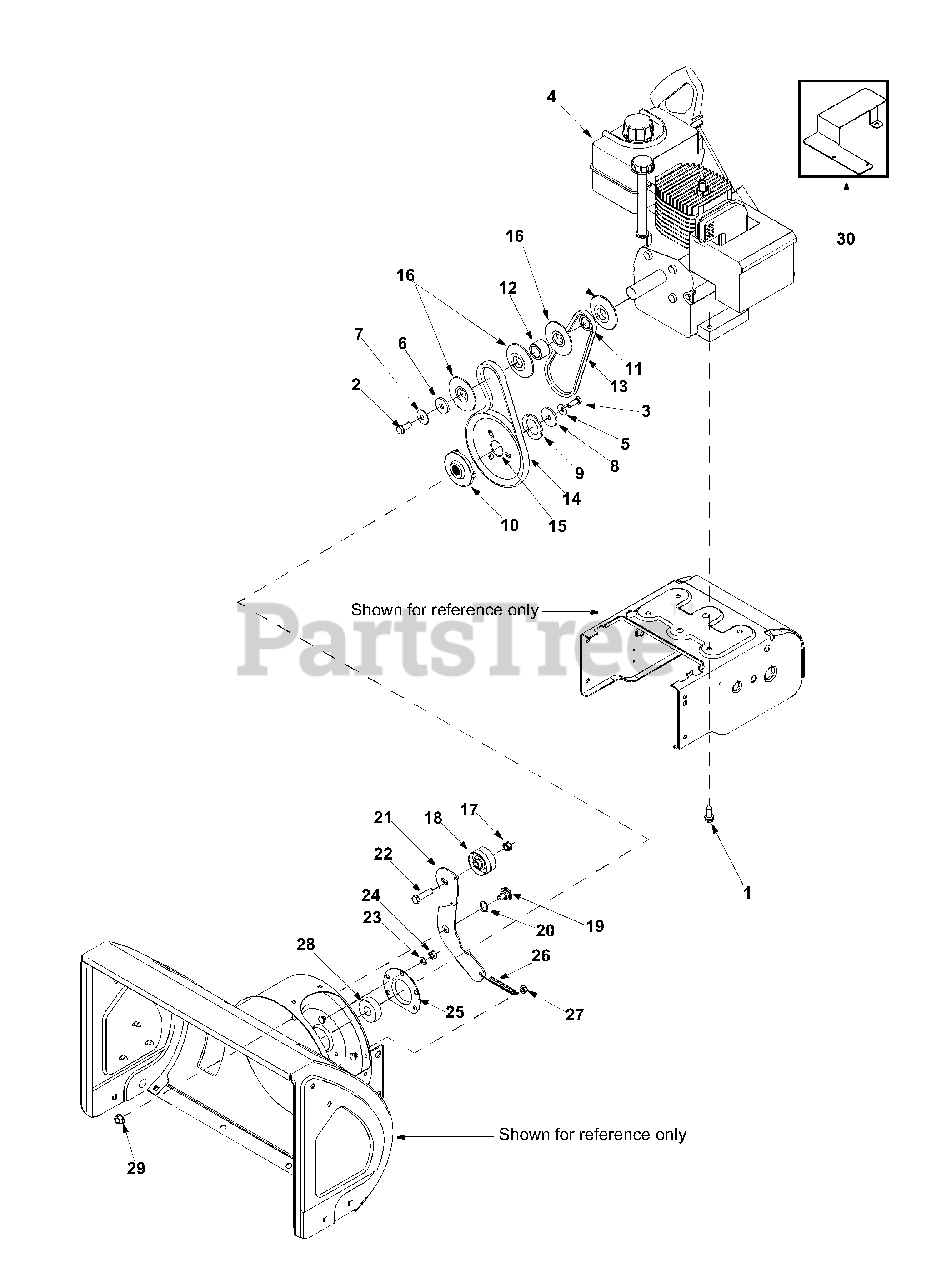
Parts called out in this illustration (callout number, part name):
1	TT Sems Screw 3/8-16 x 1.0"
2	Hex Bolt 3/8-24 x 0.875"
3	Lock Bolt 5/16-24 x 0.875"
4	Engine
5	Bell Washer
6	Flat Washer
7	Bell Washer
8	Flat Washer
9	Special Washer
10	Pulley: Adapter
11	Spacer
12	Spacer
13	V-Belt
14	V-Belt
15	Auger Pulley
16	Pulley Half
17	Hex Lock Nut 3/8-16
18	Flat Idler
19	Shoulder Screw 3/8-16
20	Wave Washer
21	Auger Idler Bracket
22	Hex Bolt 3/8-16 x 1.50"
23	Lock Washer 5/16
24	Hex Nut 5/16-18
25	Bearing Housing
26	Extension Spring
27	Patch Nut
28	Ball Bearing
29	Flange Lock Nut
30	Heat Shield: Muffler Guard
